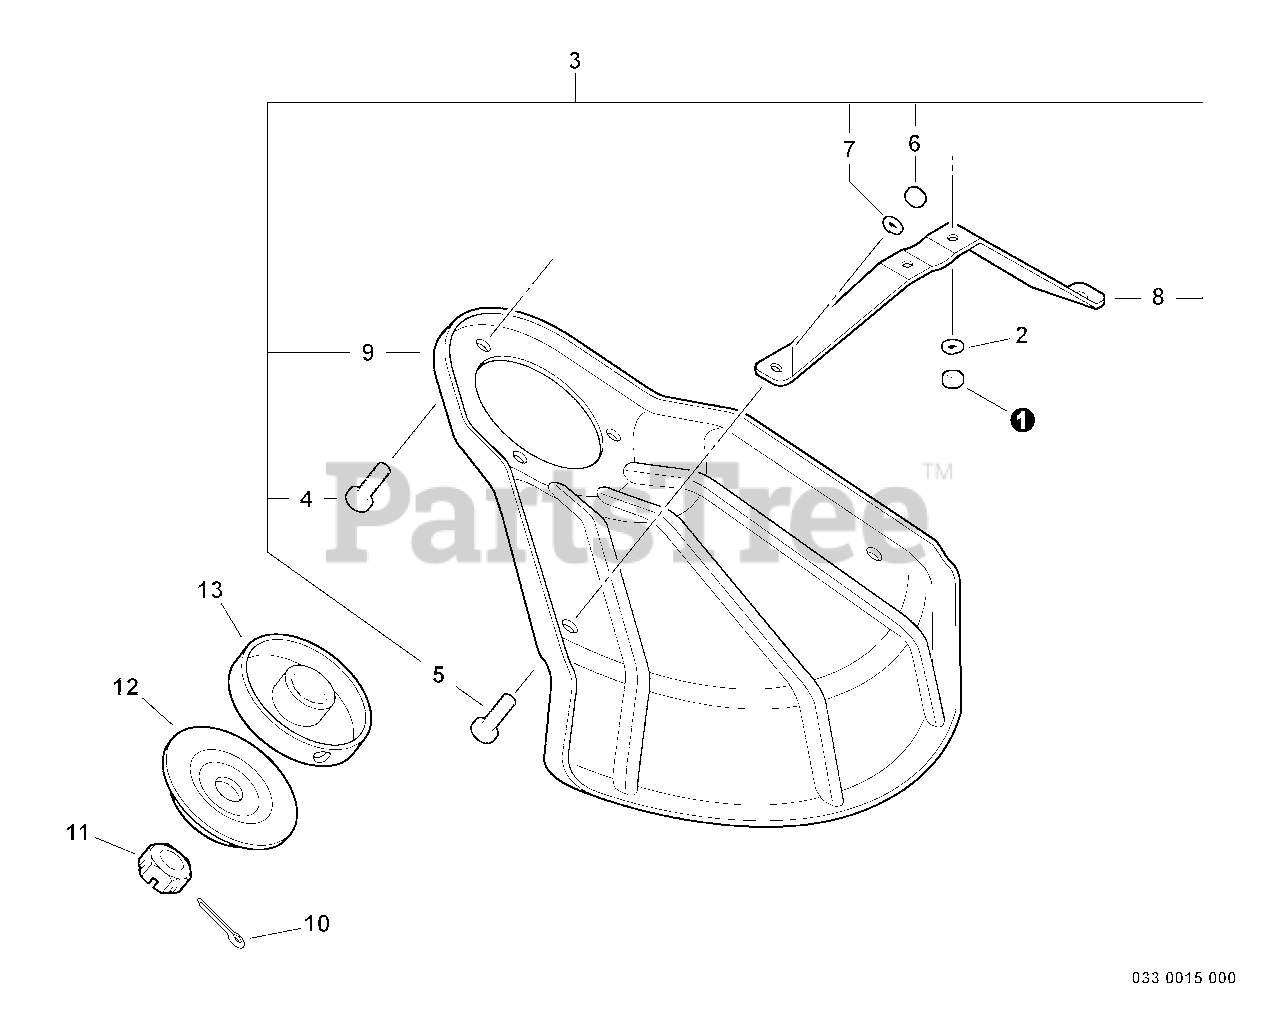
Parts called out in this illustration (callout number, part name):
1	NUT M5
2	WASHER, SPRING 5
3	SHIELD ASSY, METAL DEBRIS
4	SCREW 5×10
5	SCREW 5×8
6	NUT M5
7	WASHER, SPRING 5
8	BRACKET, SHIELD MOUNTING
9	SHIELD, METAL DEBRIS
10	PIN, COTTER 2×22
11	NUT 10×1.25 LH
12	PLATE, ADAPTOR - LOWER
13	PLATE, ADAPTOR - UPPER
